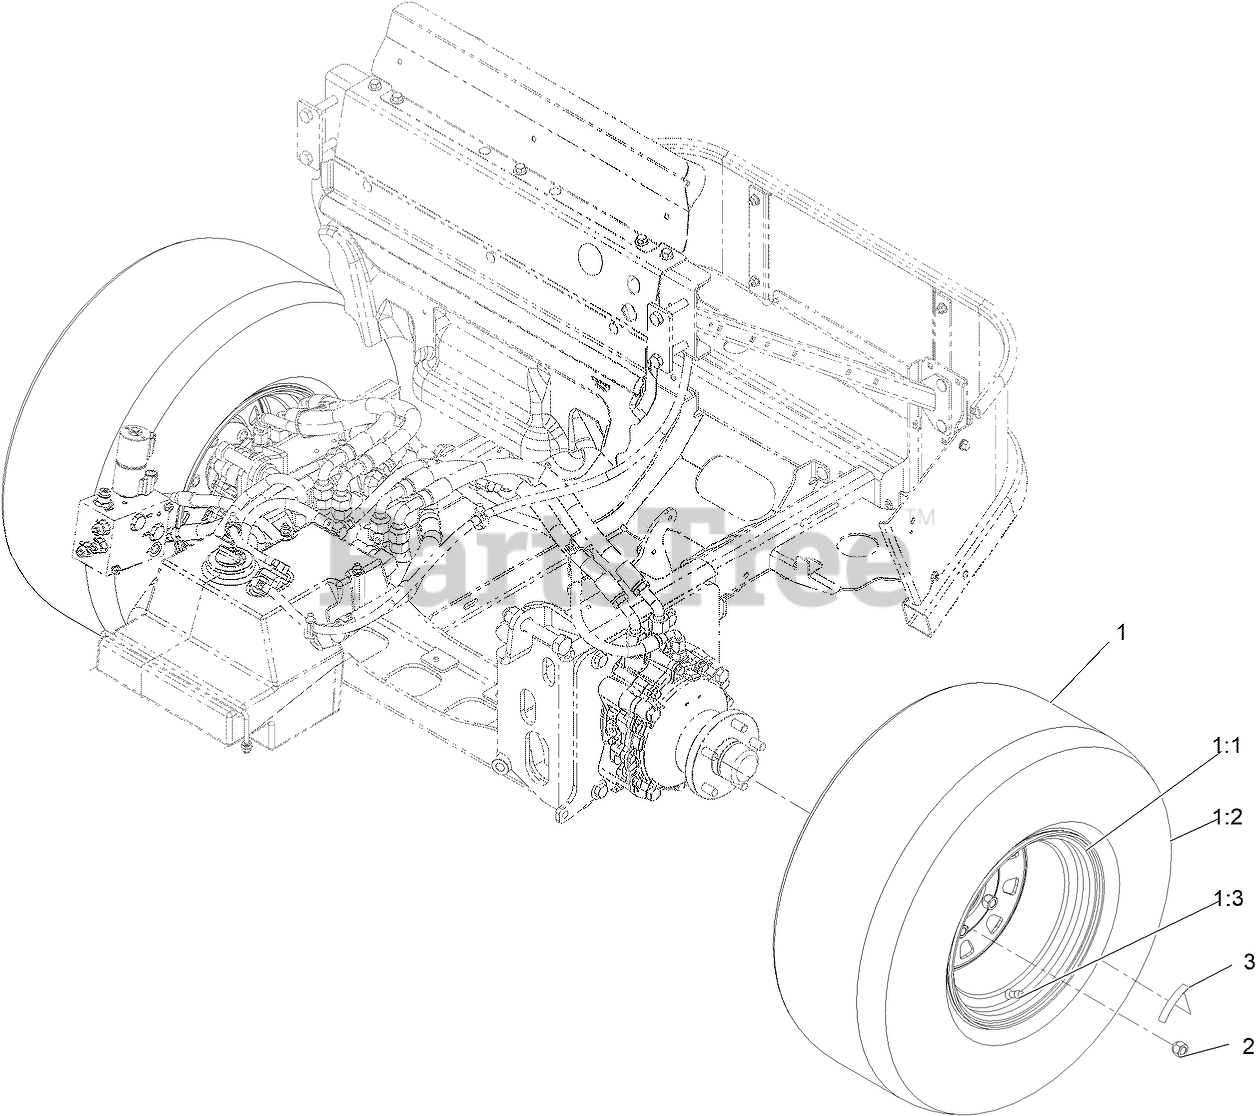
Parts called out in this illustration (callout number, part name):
1	ASM-TIRE 26X12-12, 1.0 OFFSET
1:1	RIM ASM, 1.0 OFFSET
1:3	Stem-Valve
2	NUT-LUG
3	DECAL-TORQUE, WHEEL NUT
